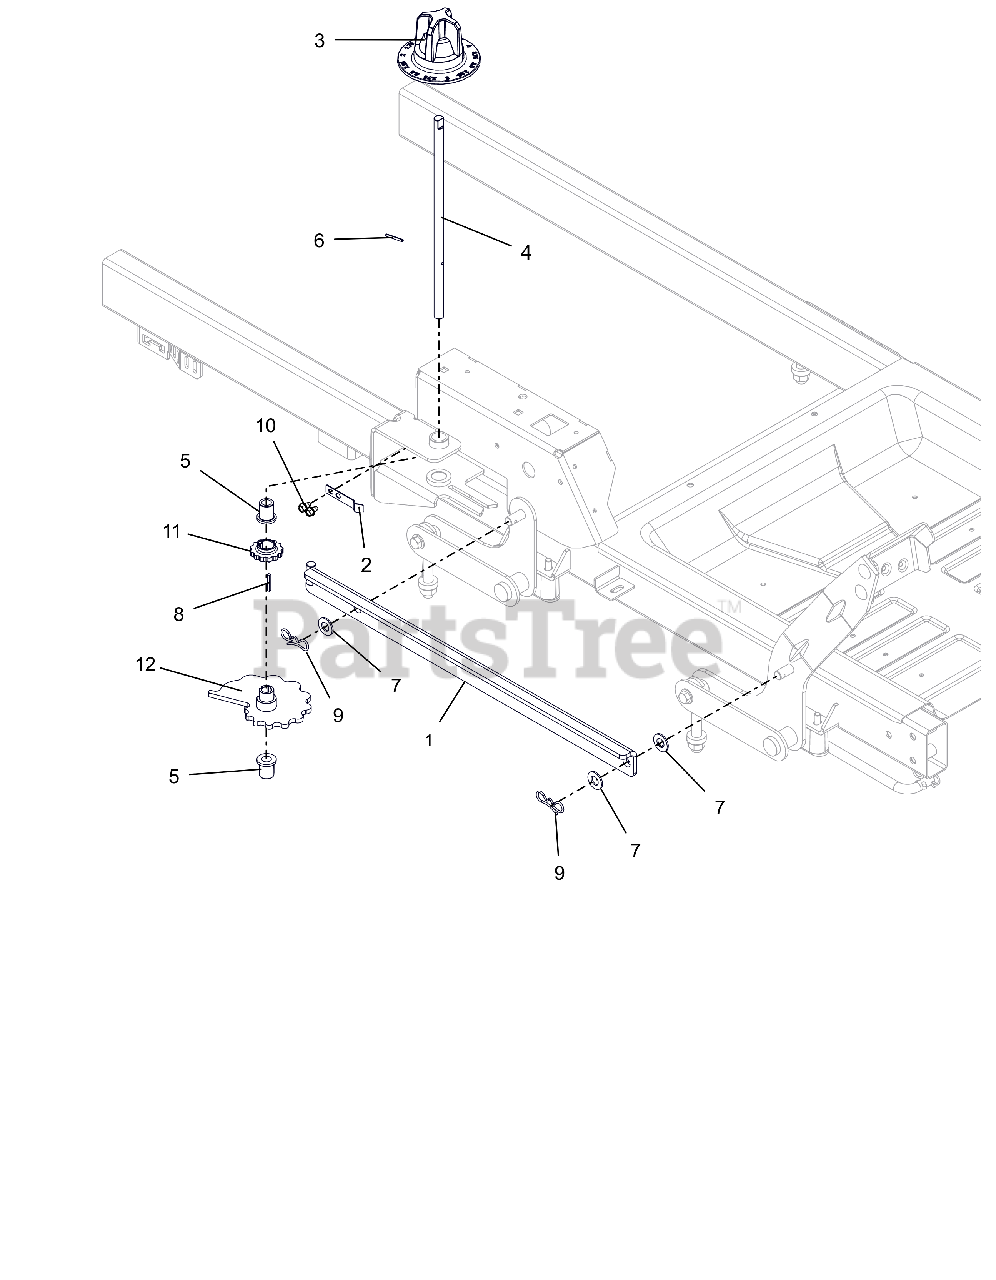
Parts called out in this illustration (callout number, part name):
1	WLDMT, HOC LINK
2	ARM, HOC DETENT
3	KNOB, HOC DIAL
4	SHAFT, HOC CAM IKON
5	BSHG-FLG, .503X.750X.875X1.00
6	PIN-ROLL .125X1.00
7	WSHR-FL-NYL .518X1.000X.080
8	KEY, 1/8 X 1/8 X 1.0
9	PIN,BOW TIE LOCKING .091X1.875
10	SCR,TAP .25-20X.375 HWH TR ZCC
11	GEAR, HOC INDEX
12	WLDMT, HOC CAM
